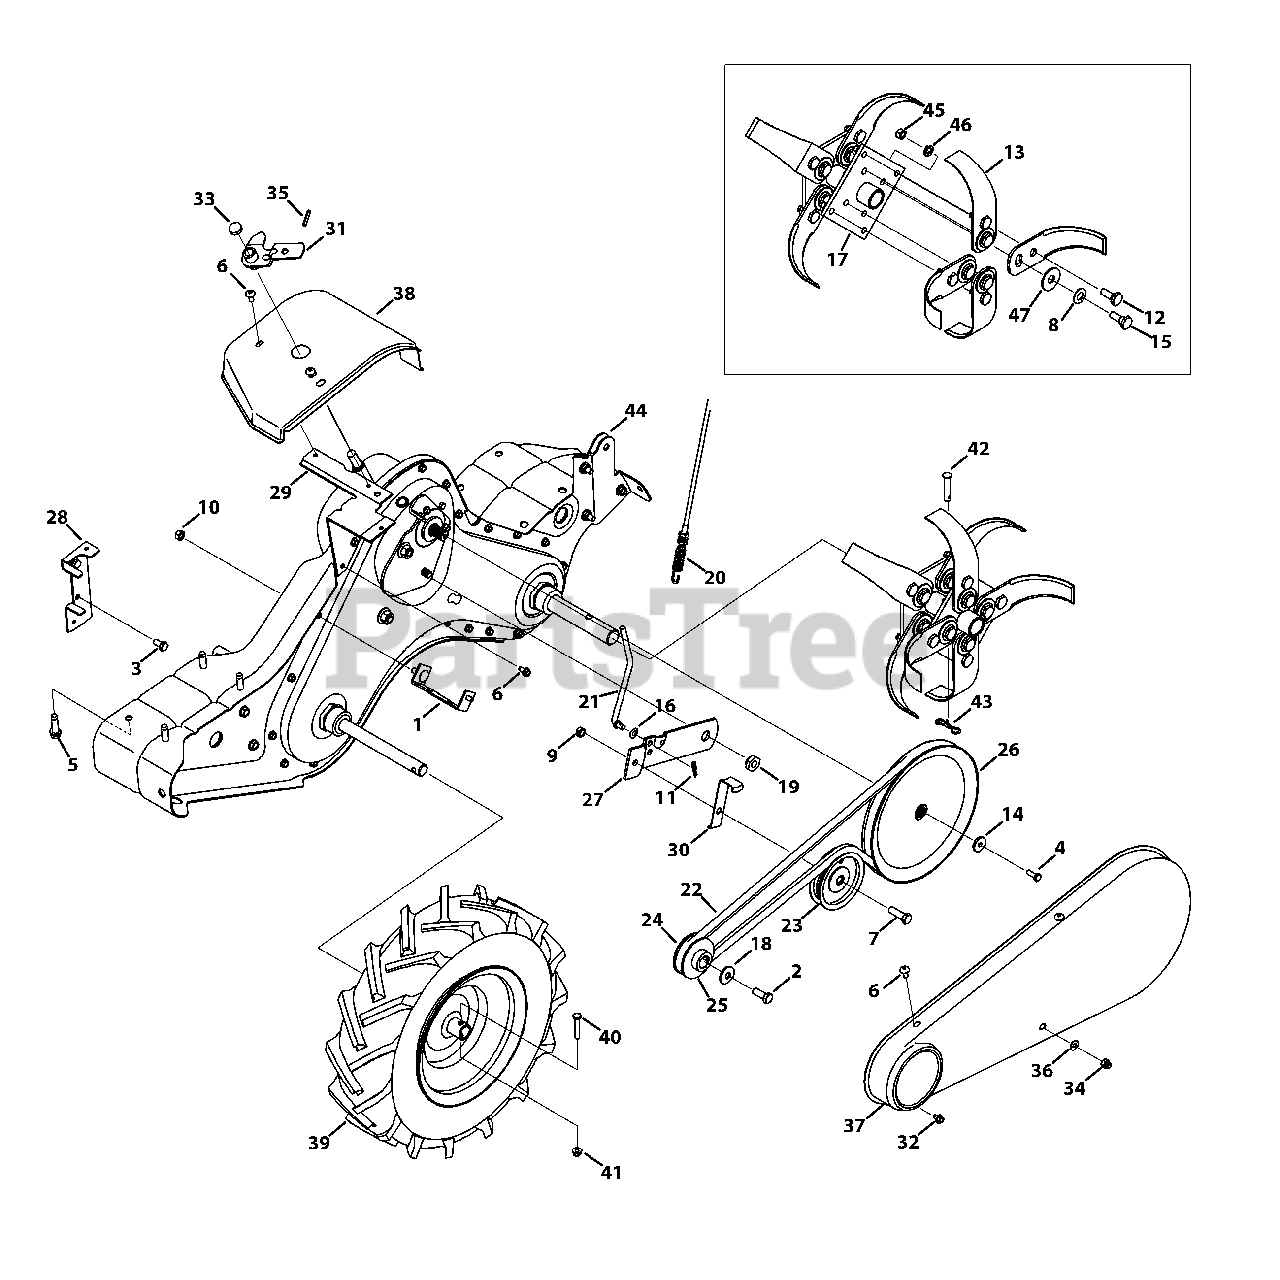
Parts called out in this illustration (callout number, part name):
1	Belt Cover Bracket Assembly
2	Hex Head Screw, 3/8-24 x 1.00
3	Hex Bolt, 5/16-24 x .625
4	Hex Bolt, 1/4-28 x .75"
5	Screw, 3/8-16 x 1.250
6	Hex Washer Screw
7	Hex Head Screw, 3/8-16 x 1.25
8	Washer, Bell, .525 x 1.00 x .050
9	Jamlock Nut, 3/8-16
10	Flangelock Nut, 5/16-18
11	Cotter Pin, .072 DIA. x 1.13 LG
12	Screw, Shoulder, 3/8-24 x 1/2 x .180
13	Articulating Tine
14	Washer, Flat, .265 x .938 x .120
15	Screw, Shoulder, 3/8-24 x 1/2 x .325
16	Washer, Spring, .317 x .625 x .020
17	Tine Adaptor Assembly
17	Tine Assembly
18	Washer, Bell, .396 x 1.140 x .095
19	Shoulder Nut, 7/16-20
20	Clutch Cable
21	Idler Pulley Rod
22	Belt, 4L x 58.16 LG
23	Flat Idler Pulley w/ Flanges, 3.75 O.D.
24	Engine Pulley, Inner Half
25	Engine Pulley, Outer Half
26	Input Pulley, 4L x 8.594
27	Idler Pulley Bracket
28	Belt Keeper Bracket, B&S 6.5 HP
29	Shift Cover Bracket
30	Idler Belt Keeper
31	Shift Crank Assembly
32	Screw, 1/4-20:0.375
34	Lock Nut, Cap, 1/4-28
35	Spiral Pin, 3/16 x 1.00
36	Washer, Flat, .271x .630 x .065
37	Belt Cover
38	Shift Cover
39	Wheel, 16 x 4.6 x 8
40	Hex Head Screw, 1/4-20 x 1.50
41	Flangelock Nut, 1/4-20
42	Clevis Pin, .375 x 1.75
43	Cotter Pin, Bow-Tie
44	Complete Gear Case Assembly
45	Hexlock Nut, 3/8-24
46	Washer, Lock, 3/8
47	Washer, Flat, .51 x 1.5 x 0.07
